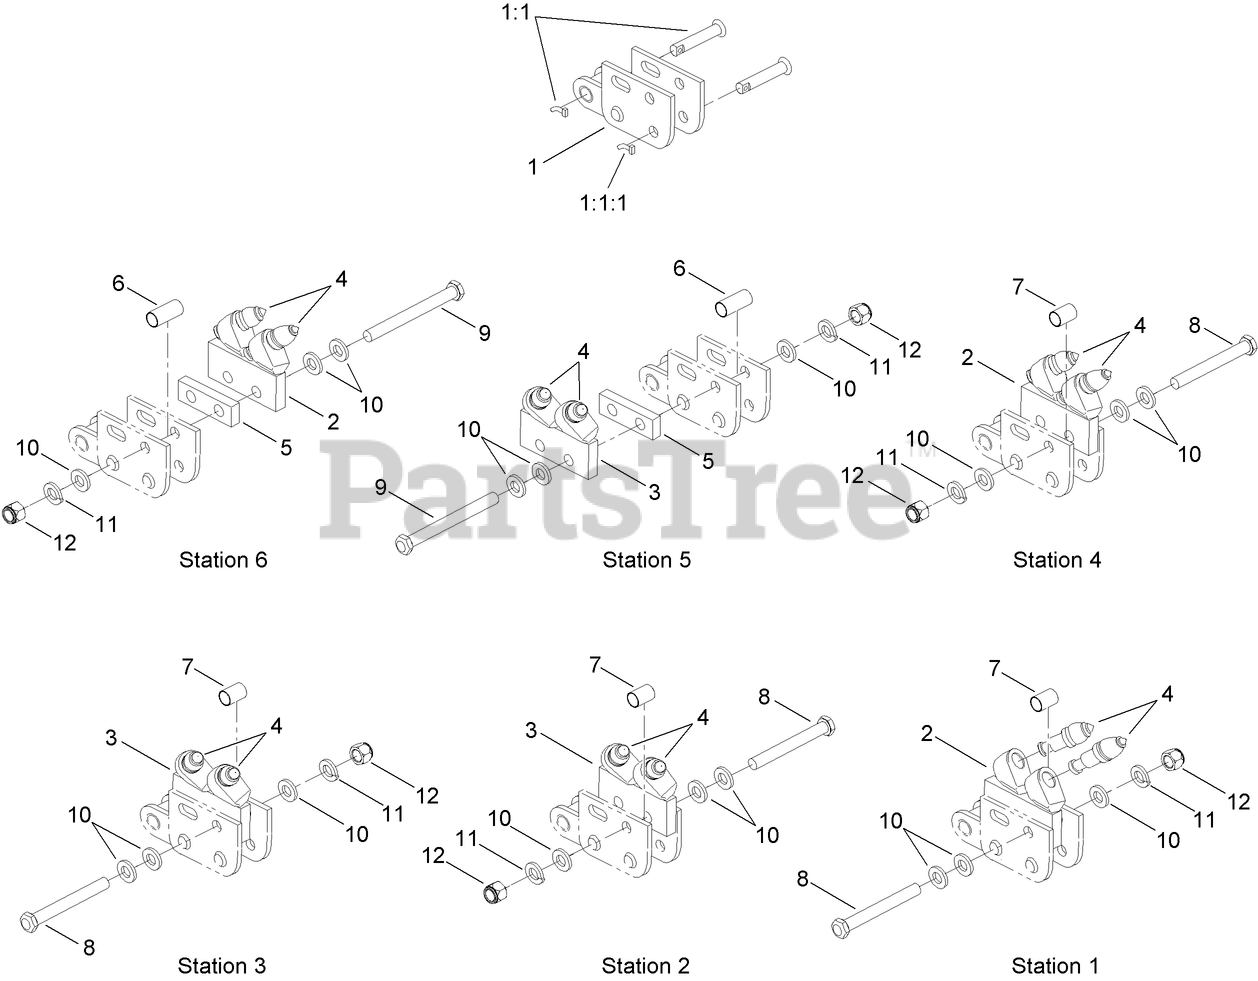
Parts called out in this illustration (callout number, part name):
1	CHAIN REPAIR LINK ASM
1:1	NOTCHED PIN AND KEEPER ASM
1:1:1	PIN-KEEPER
2	HOLDER-BIT, LH
3	HOLDER-BIT, RH
4	BIT-RETAINER, REAR
5	SPACER-FLAT
6	SPACER-TUBE, OUTSIDE MOUNT
7	SPACER-TUBE, INSIDE ADAPTER, HD
8	BOLT-HH
9	BOLT-HH
10	WASHER-FLAT
11	WASHER-LOCK
12	NUT-LOCK
